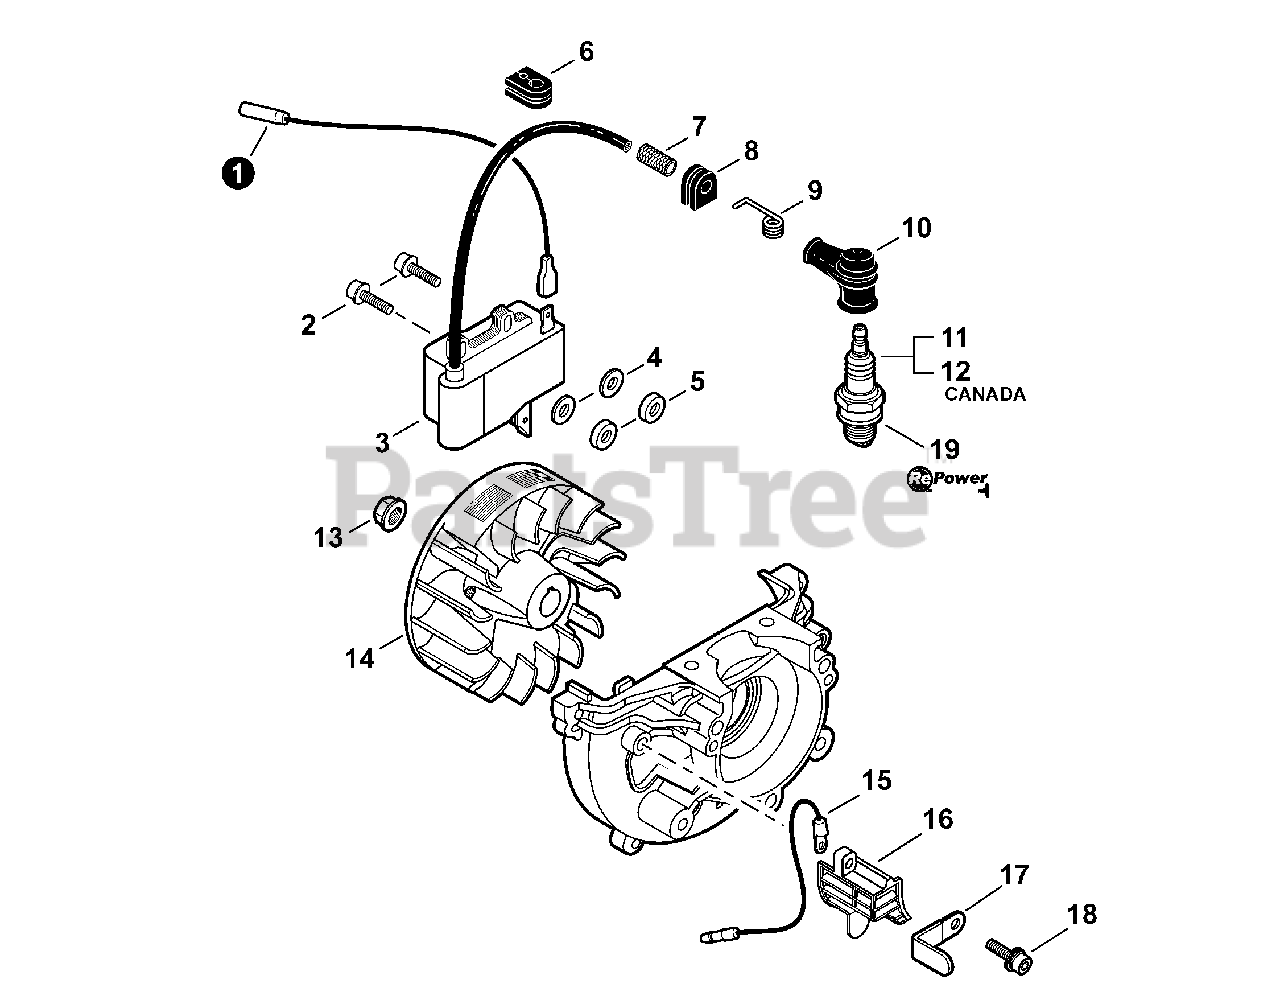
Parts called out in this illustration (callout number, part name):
1	LEAD - IGNITION
3	COIL, IGNITION
4	WASHER 4mm
5	INSULATOR 4
6	GROMMET
7	TUBE, INSULATOR
8	GROMMET, HT CORD
9	TERMINAL, SPARK PLUG
10	CAP, SPARK PLUG
11	SPARK PLUG - BPM8Y
12	SPARK PLUG - BPMR8Y
13	NUT, FLANGE M8
14	FLYWHEEL
15	LEAD - GROUND
16	COVER, DUST
18	BOLT 5×16
19	TUNE-UP KIT - REPOWER
